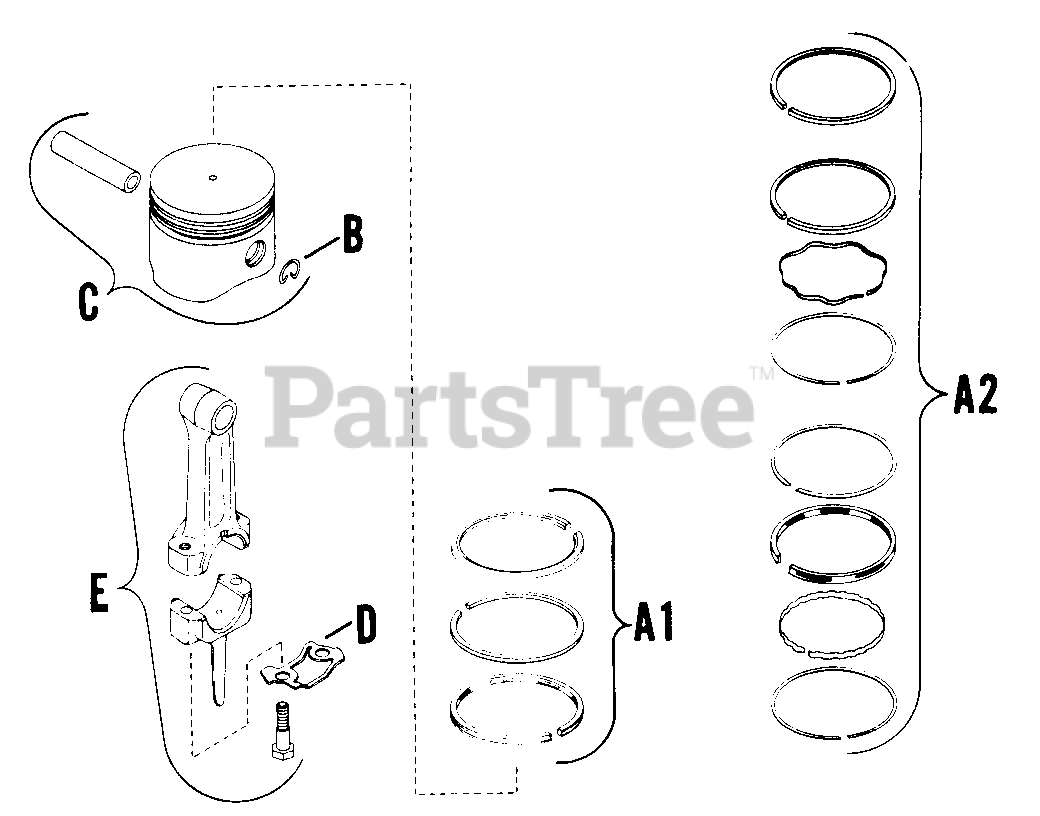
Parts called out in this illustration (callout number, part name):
A1	RINGS - USE 231424
A1	RINGS - USE 231425
A1	RINGS - USE 231426
A1	RINGS - USE 231427
A2	RINGS STD.
A2	RINGS .010
A2	RINGS .020
A2	RINGS .030
B	RING, RETAINING
C	PISTON SET - USE 41 874 01
C	PISTON SET - USE 41 874 02
C	PISTON SET - USE 41 874 03
C	PISTON SET - USE 41 874 04
D	LOCK, CONN ROD - DISCONTINUED
E	ROD STD.
E	ROD .010 (KM) - DISCONTINUED
